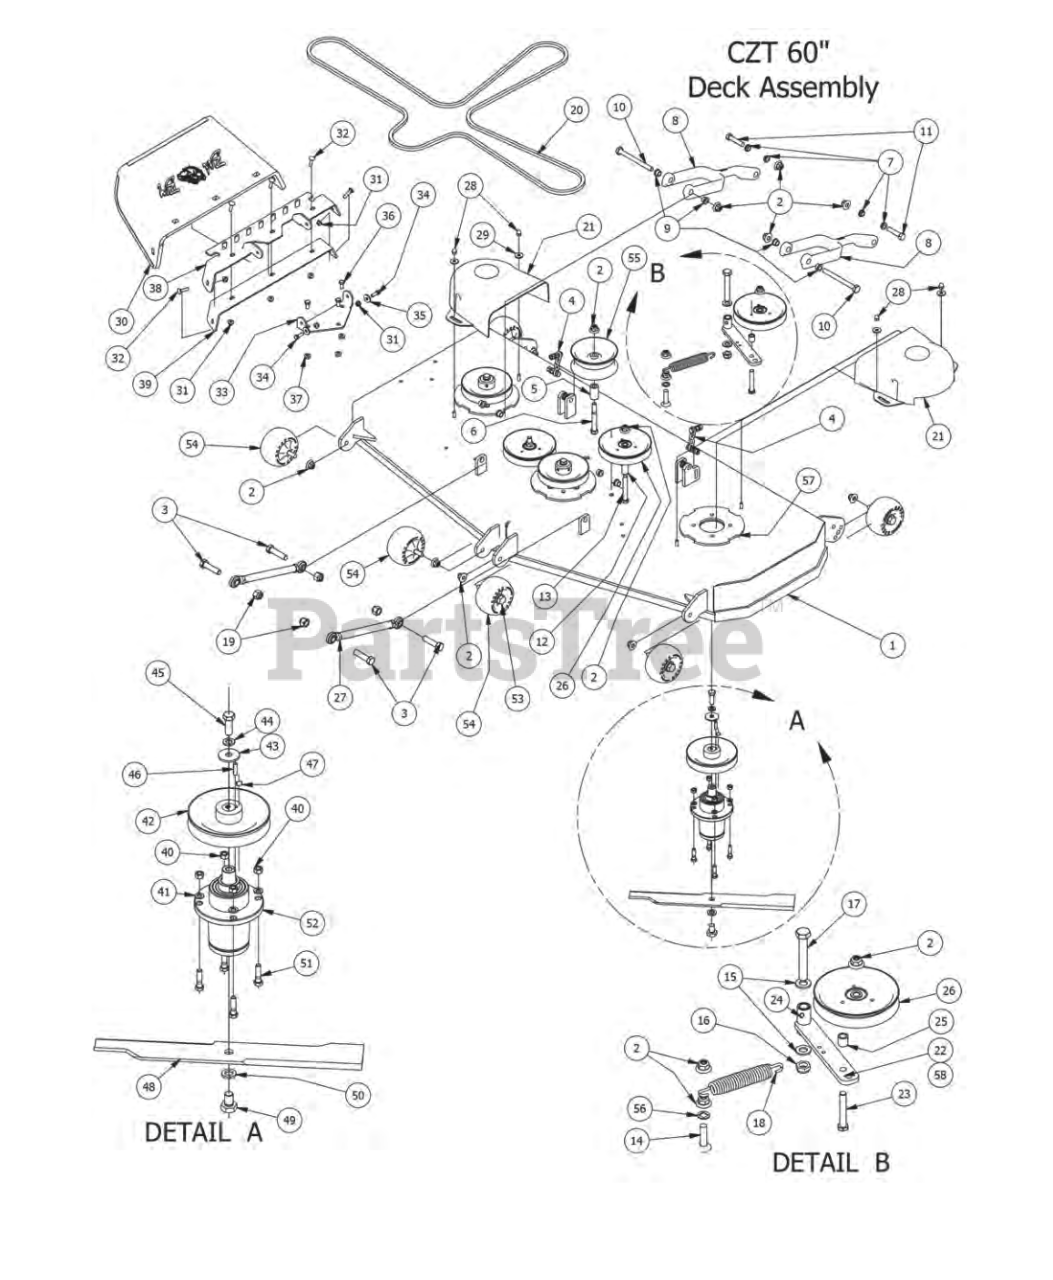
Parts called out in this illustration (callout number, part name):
1	2014 60" ZT/ CZT Deck
2	1/2-13 Nylon Flange Nut-Orange
3	5/8" x 2 1/2" Gr5 Hex Bolt (Coarse)
4	2015 CZT Deck Hanger Chain
5	1 3/4" Pulley Spacer
6	1/2" x 4" Bolt (Grade 8)
7	Flange for Lower Deck Arm
8	Deck Arm Assembly
9	Flange Bushing For Deck Arm upper
10	1/2" x 5 1/2" Bolt
11	1/2-13X 2-1/4 GR Hex Bolts
12	502 ID X.75 OD X 1.500 Leng
13	1/2 x 3 1/2 Flange Bolt Grade 8
14	1/2 x 2" Carriage Bolt
15	.635 ID Plastic Washer
16	5/8-11 Nylon Insert Jam Half Nut
17	5/8" x 4" Hex Bolt
18	2009 Deck/Pump Idler Spring
19	5/8 Std NC Nylock Nut
20	60" ZT Deck Belt
21	2014 ZT Pulley Cover
22	Deck Idler
23	1/2-13 x GR 5 Hex Bolt Zinc
24	1/4" Press in Grease Fitting.
25	3/4 OD x 1/2 ID x 314 Length
26	5-3/4 Idler Pulley
27	Turnbuckle (Top Link)
28	Acom nut-pulley Cover
29	360 ID Plastic Washer-Black
30	Rubber Discharge Chute
31	5/16" Nylon Flange Nut
32	5/16" x 1 1/4" Carriage Bolt
33	Discharge Chute Hanger (deck mounted)
34	5/16" x 1" Bolt
35	360 ID Plastic Washer
36	3/8" x 3/4" Hex Bolt
37	3/8" Flange Nut
38	60" Discharge Chute Upper Hanger
39	60" Lower Hanger
40	3/8" Hex Nut
41	3/8" Lock Washer
42	6 1/4" Drive Pulley
43	1/2 Belleville Washer
44	1/2" Lock Washer
45	1/2"-20 x 1 1/2 - Grade 5 Fine Thread Bolt
46	1/4" x 1" Key
47	5/16 Set Screw
48	60 Inch Fusion Blade
49	5/8" x 1 1/2" Gr8 Hex Bolt (Fine)
50	5/8" Lock Washer
51	3/8" x 1 1/2" Hex Bolt
52	ZT/CZT SPINDLE ASSEMBLY
53	Deck Wheel Bolt
54	Anti-Scalp Rollers
55	5 3/4" Deck Idler Pulley
56	517 Square Hole Round Washer
57	Deck Spindle Support Plate 72 inch
58	Deck Idler Assembly (Components 33,34,35,36,37)
